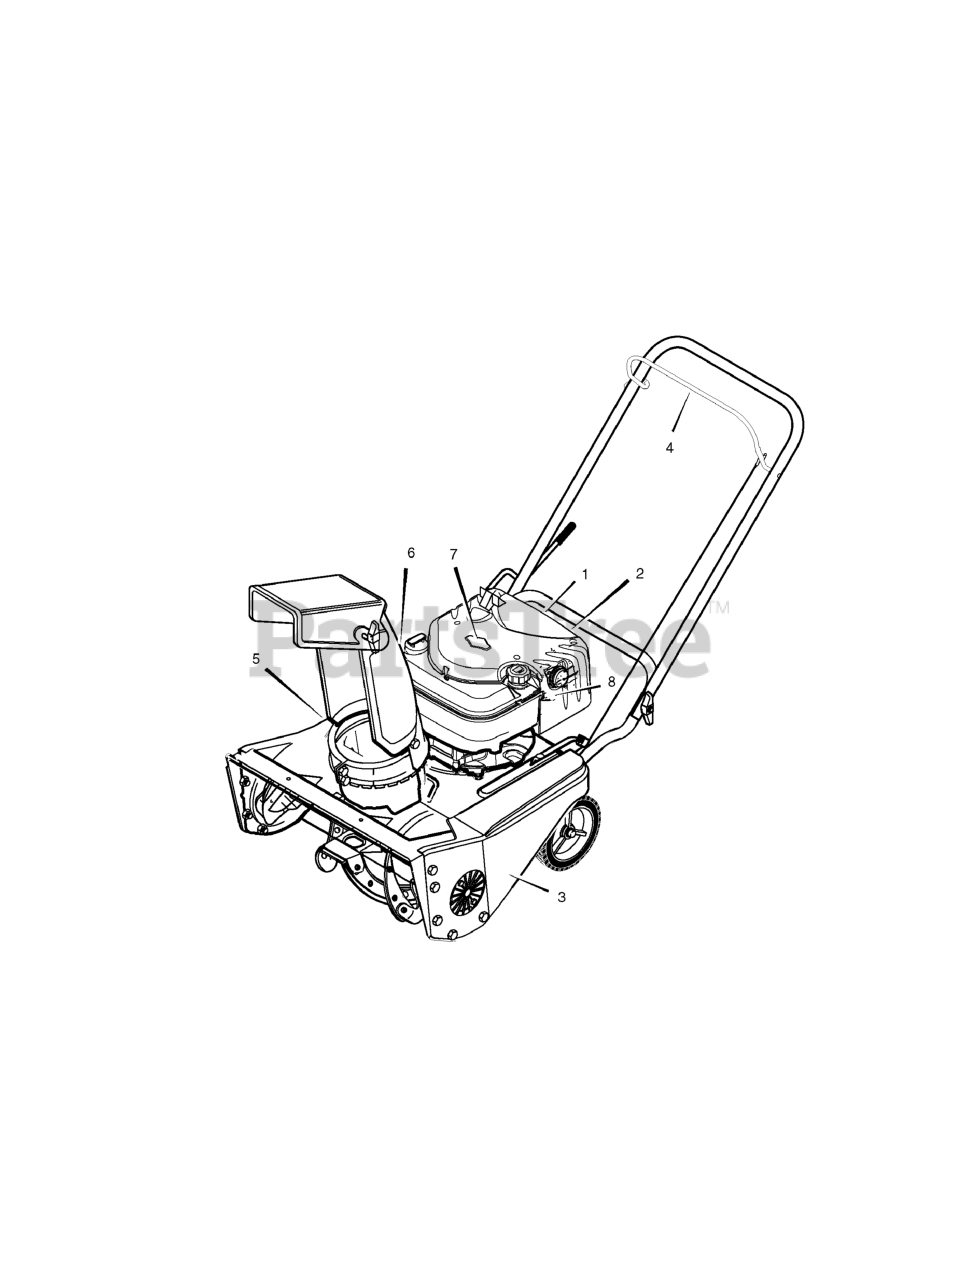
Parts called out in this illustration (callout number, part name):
1	Decal, 4hp / 21"
2	Decal, Choke
3	Decal, Belt Instruction (inside cover)
4	Decal, Auger Control Lever
5	Decal, Danger Auger (Foot)
6	Decal, Danger Chute (Hand)
7	Decal, Briggs & Stratton
8	Decal, Primer Bulb
